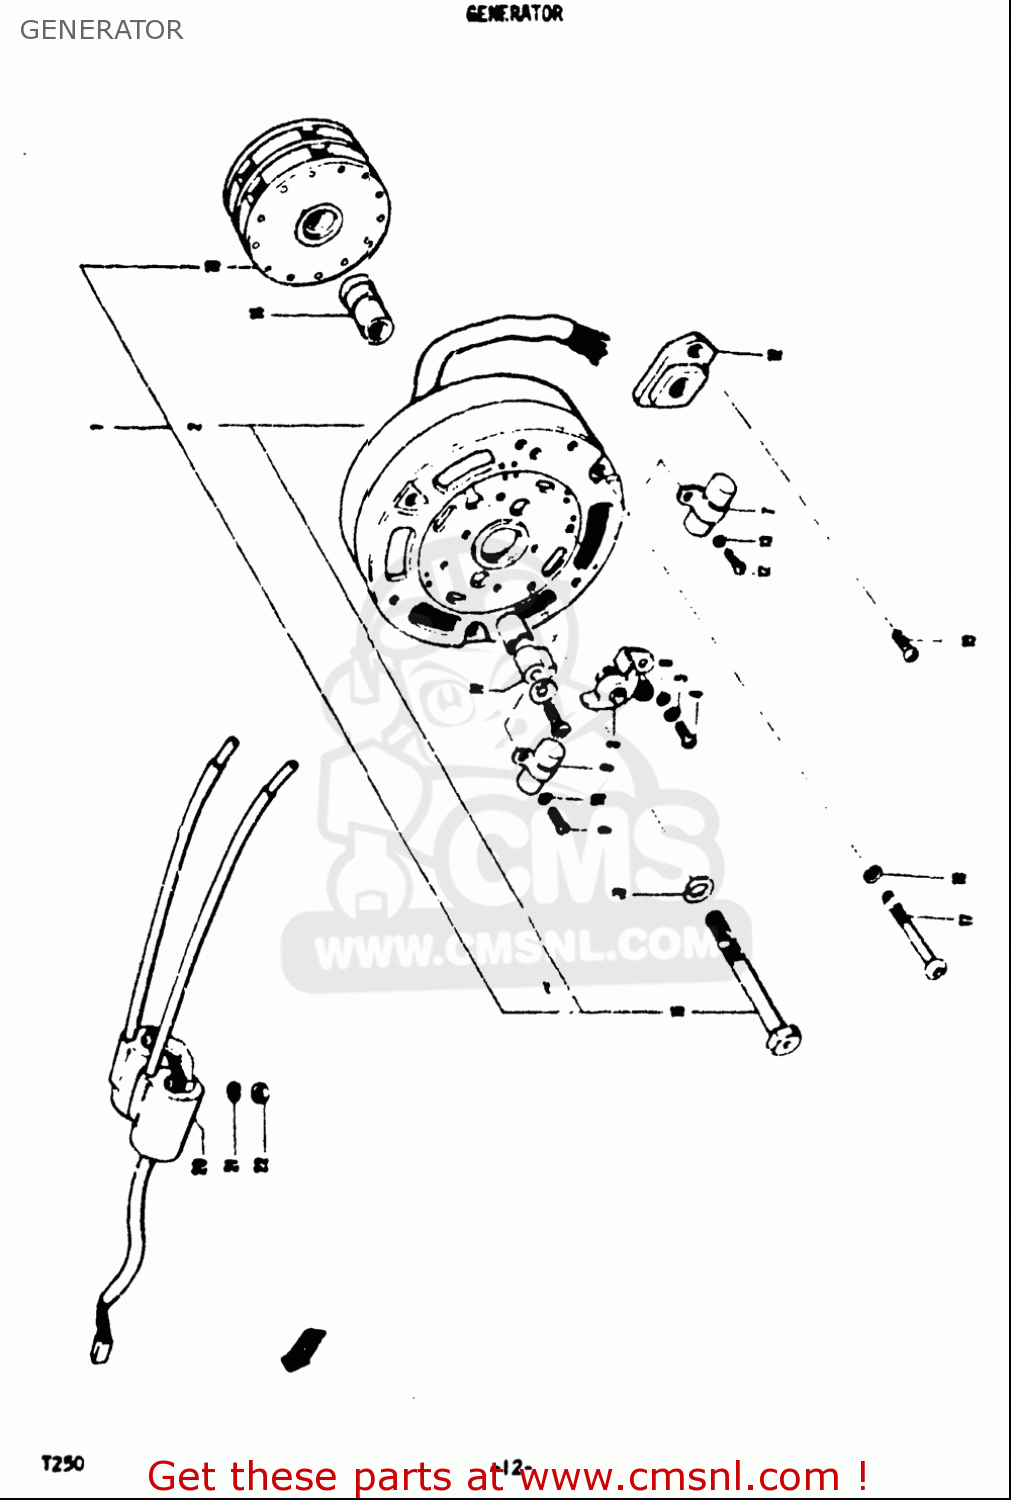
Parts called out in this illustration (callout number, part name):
3	POINT ASSY,CONTACT
5	WASHER,LOCK
6	WASHER
7	CONDENSER,R
8	CONDENSER,L
10	WASHER,LOCK
11	.FELT, OIL
16	WASHER,LOCK
17	SCREW
18	WASHER,LOCK
20	COIL ASSY,IGNITION
21	WASHER,LOCK
22	NUT
